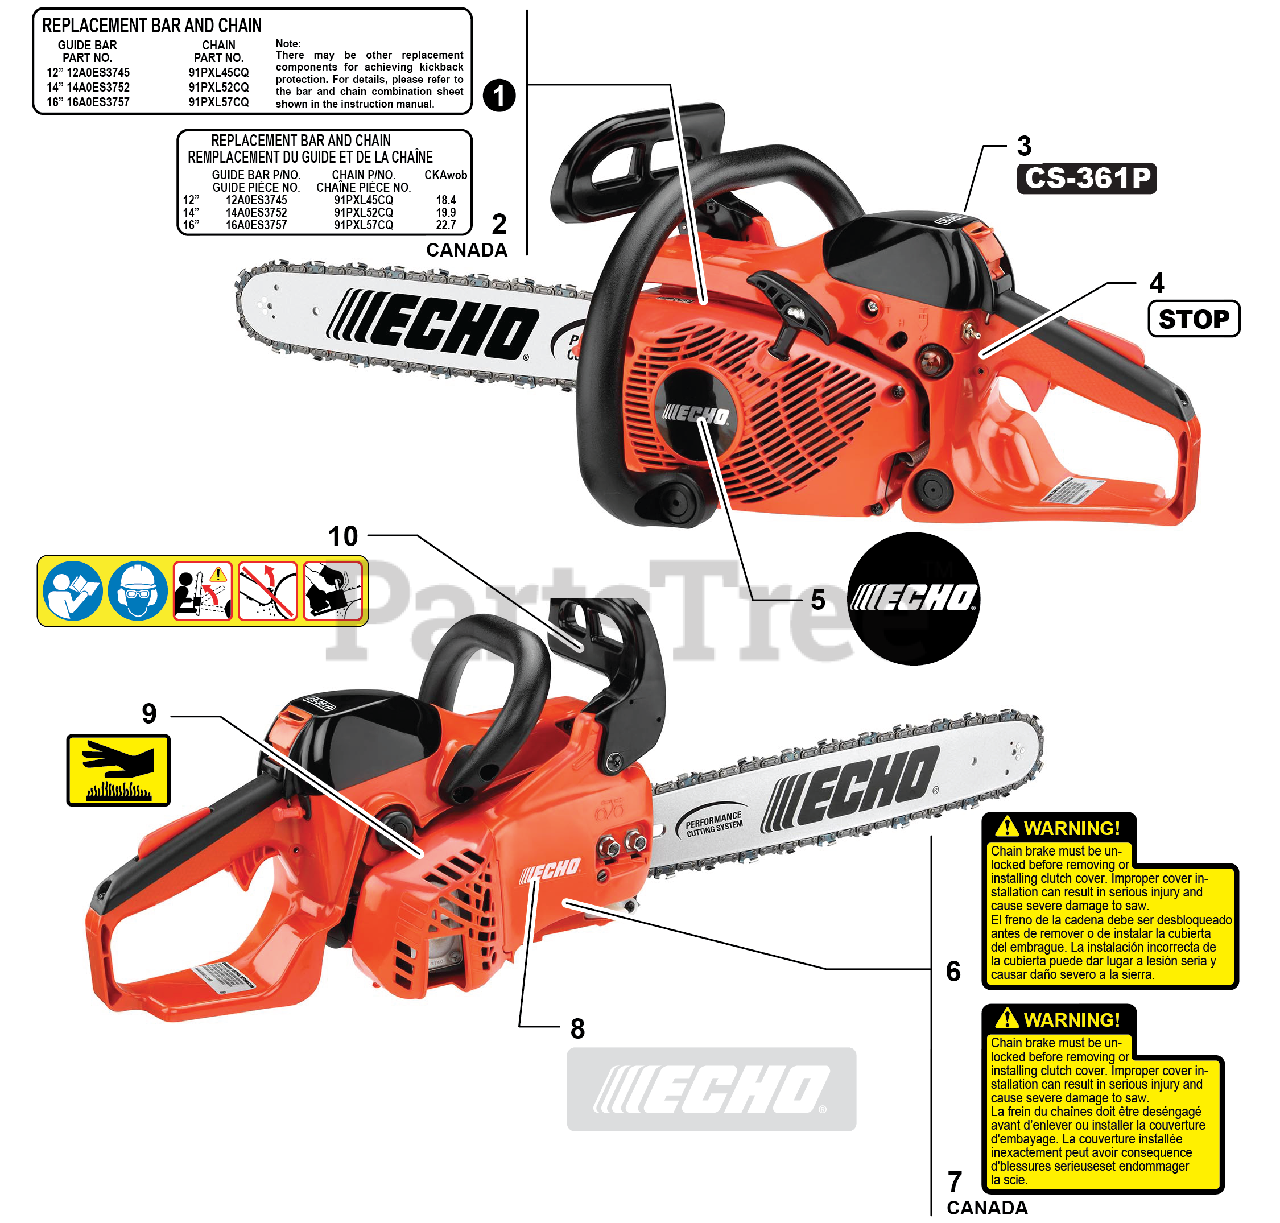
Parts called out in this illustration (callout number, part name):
1	LABEL, BAR & CHAIN
2	LABEL, BAR & CHAIN
3	LABEL, MODEL CS-361P
4	LABEL, STOP
5	LABEL, ECHO
6	LABEL, WARNING
7	LABEL, WARNING
8	LABEL, ECHO
9	LABEL, CAUTION - HOT
10	LABEL, CAUTION
